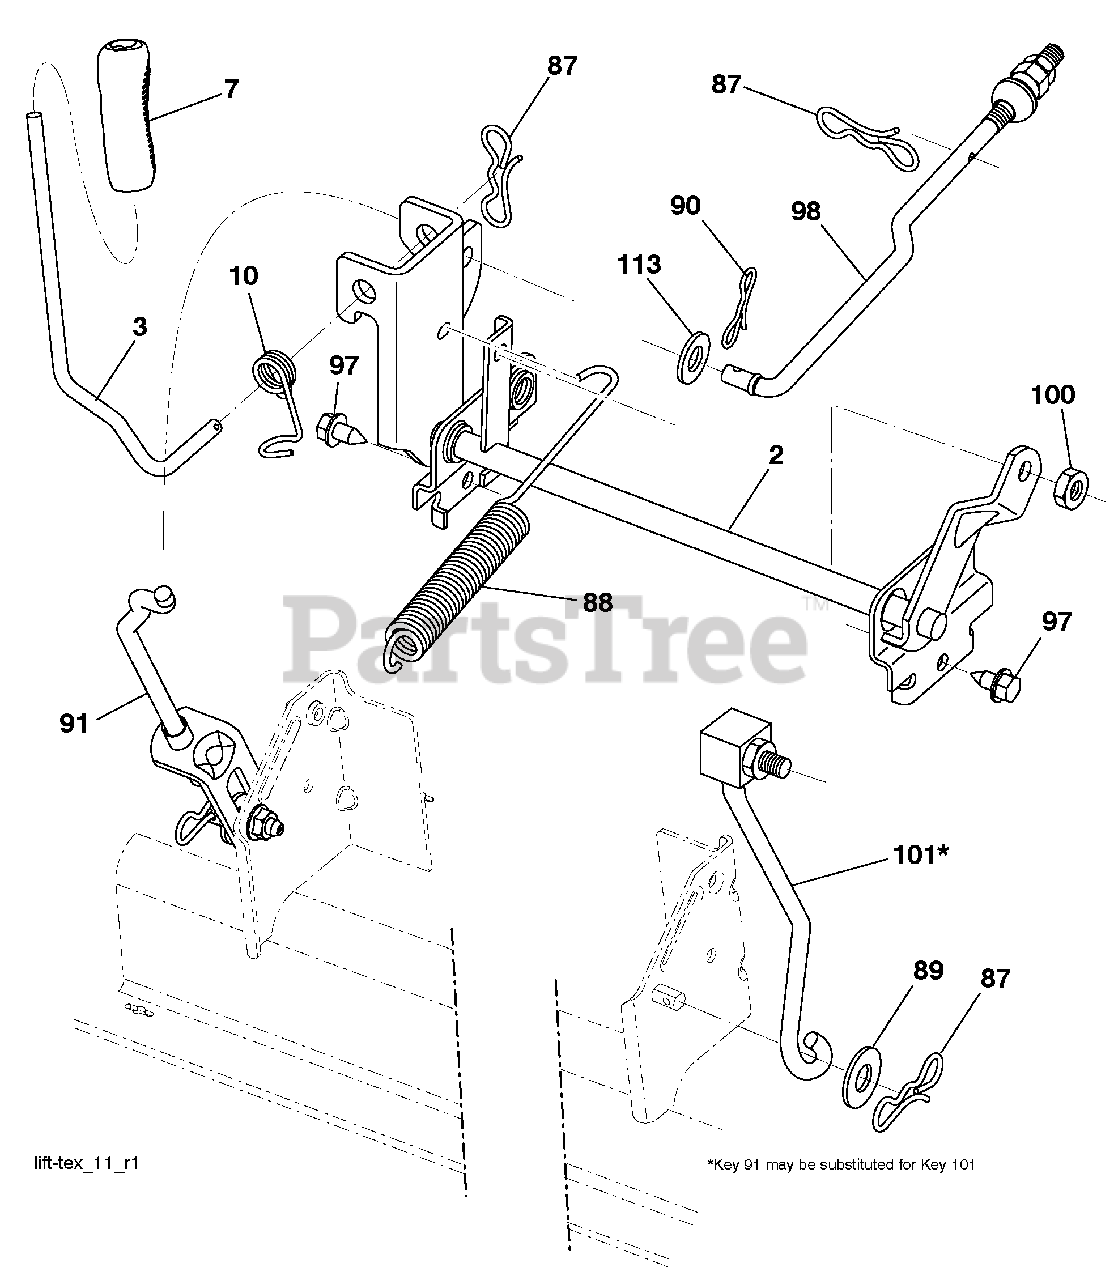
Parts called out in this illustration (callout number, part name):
2	Shaft Asm., Lift
3	Lever Asm., Lift RH
7	Grip, Lever
10	Spring Torsion
87	Pin Cotter 7/16 Bow Tie Lock
88	Spring Lift Assist
89	Washer Clear Zinc
90	Pin Cotter 5/16 Bow Tie Lock
91	Link Lift Susp Mower Rear
97	Screw 3/8-16 x .75
98	Link Lift Susp. Front Mower
100	Nut Lock 3/8-16 unc
101	Link Asm lift
113	Washer 17/32 x 1-3/6 x 12 Ga.
